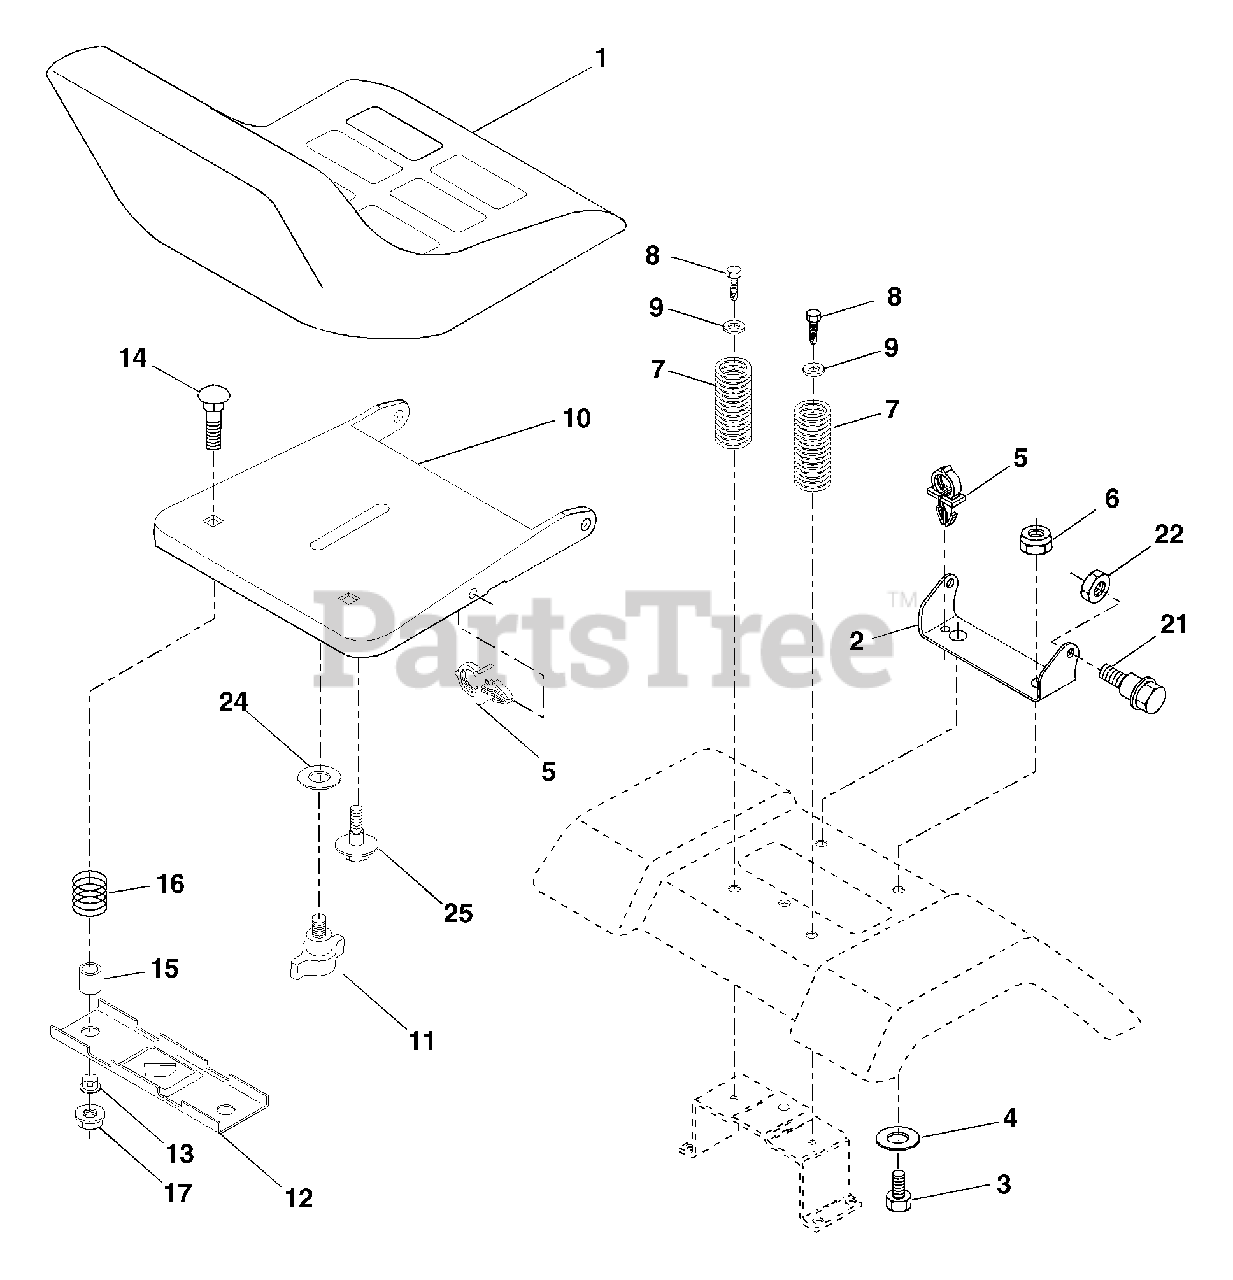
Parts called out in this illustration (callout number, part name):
1	Seat
2	Bracket Pivot Seat 8 720
3	Bolt Fin Hex 3/8-16 x 1
4	Washer Flat 13/32 x 1.0 x 10 Ga.
5	Clip Push-In
6	Nut Hex w/Ins. 3/8-16 Unc
7	Spring Seat Cprsn 2 250 Blk Zi
8	Screw 3/8-16 x 1
9	Washer 13/32 x 1.0 x 14 Ga.
10	Pan Seat
11	Knob Seat Adj Wingnut
12	Bracket Mounting Switch
13	Bushing Snap Blk Nyl 50 Id
14	Bolt Rdhd Sqnk 1/4-20x1-1/2
15	Spacer Split 28 x .88 Zinc
16	Spring Cprsn Plate
17	Nut Lock 1/4 Lge Flg Gr 5 Zinc
21	Bolt Shoulder 5/16-18 Unc
22	Nut Hex Lock W/Ins 5/16-18
24	Washer 17/32 X 1 -3/16 X 12 Ga.
25	Bolt Shoulder 5/16-18 X 62
